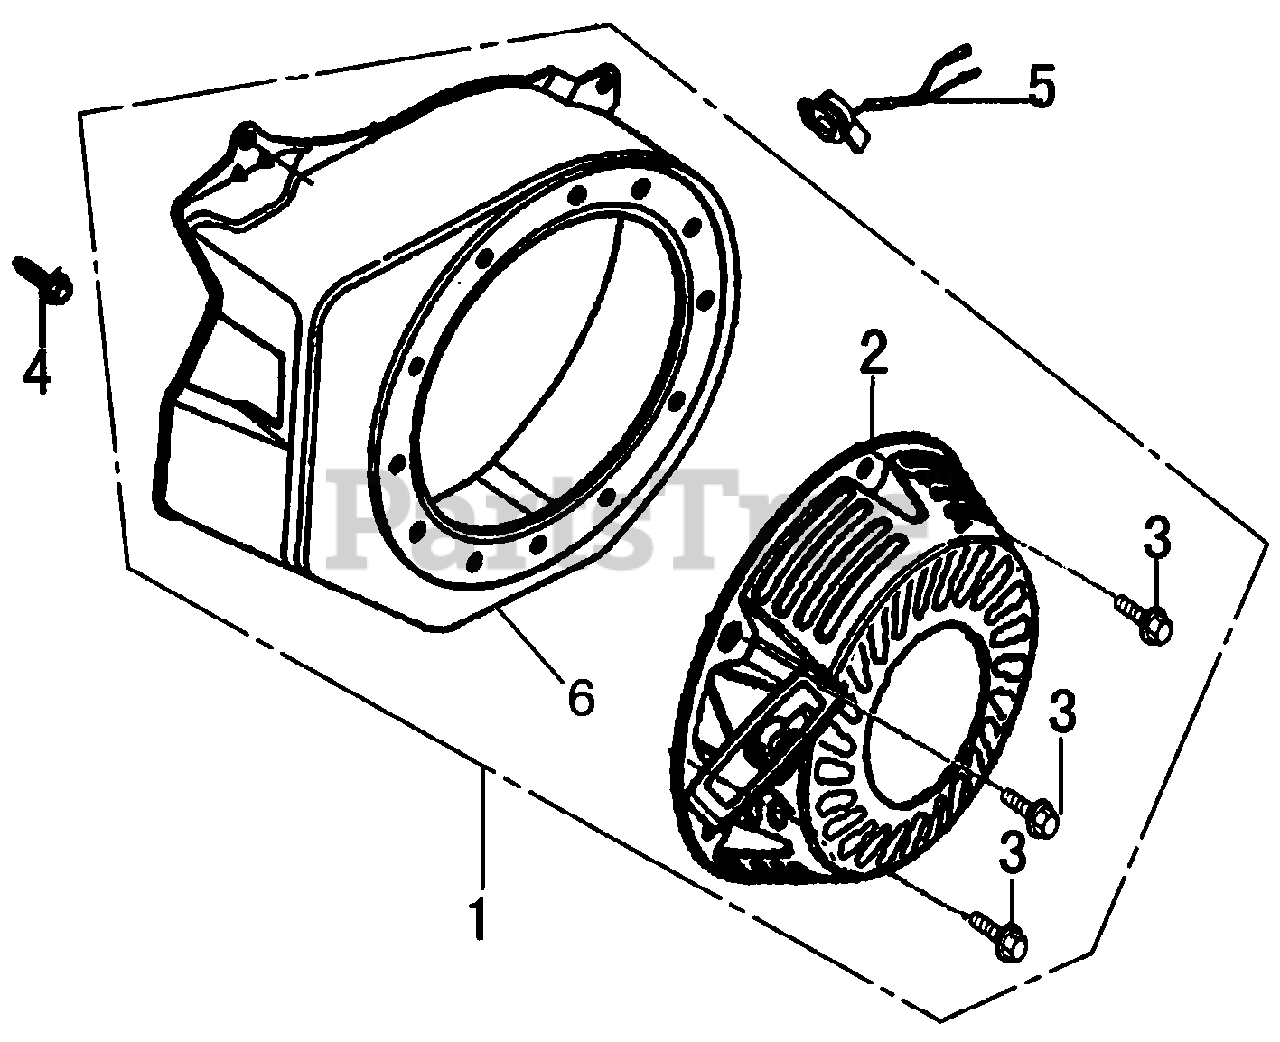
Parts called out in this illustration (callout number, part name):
1	RECOIL STARTER W/ BLOWER HSING
2	ASSY, RECOIL STARTER
3	BOLT, FLANGE 6×8
4	BOLT, FLANGE 6×10
5	SWITCH ASSY., ENGINE STOP
6	BLOWER HOUSING
